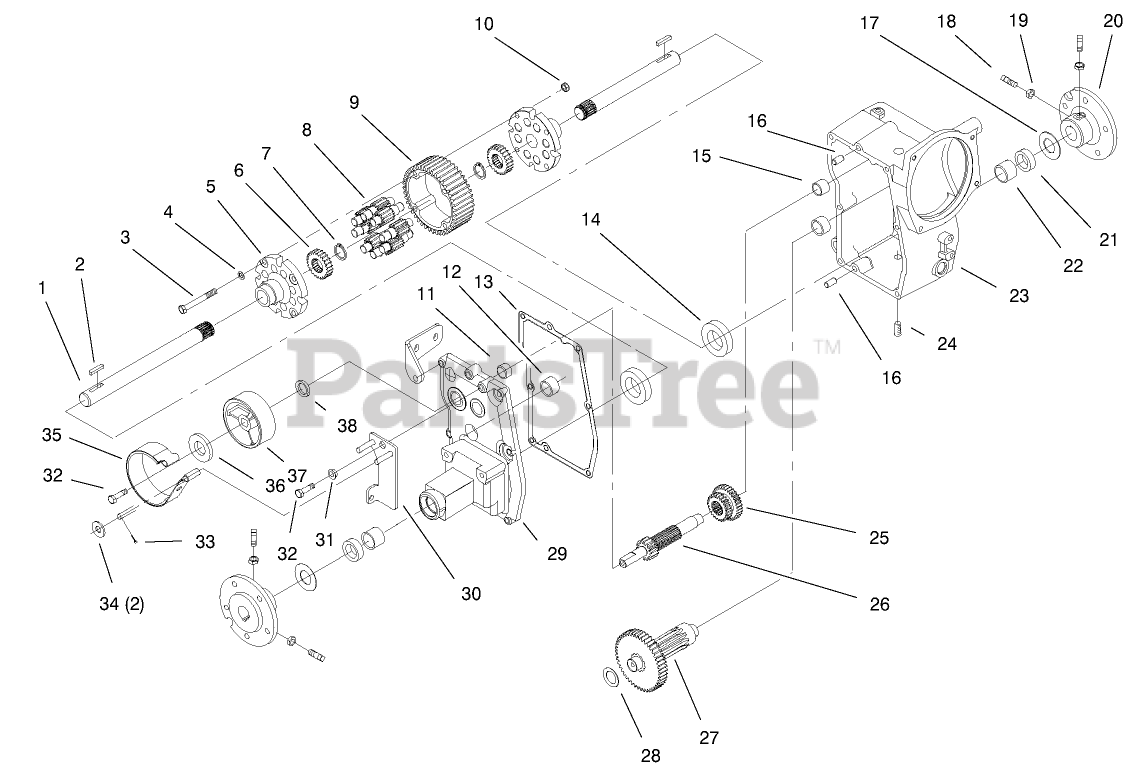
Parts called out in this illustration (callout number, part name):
1	AXLE-REAR
4	WASHER
5	END CAP-DIFFERENTIAL
6	GEAR-AXLE DIFFERENTIAL
7	RING-SNAP
8	GEAR-PINION, 11T
9	GEAR-DIFFERENTIAL RING, 43T
10	NUT-HEX
11	BEARING-NEEDLE
13	GASKET-CASE
14	BEARING-BALL
15	BEARING-NEEDLE
16	PIN-LOCATING
17	WASHER-THRUST
18	SCREW-SET, SQH
19	NUT-JAM
20	HUB-WHEEL
21	SEAL-OIL
22	BEARING
24	PLUG-PIPE
25	GEAR-SLIDING
26	SHAFT-BRAKE
27	GEAR ASM
28	WASHER-THRUST
30	ARM-PIVOT, BRAKE (BLACK)
31	CAM-SPACER
32	SCREW-HH, LOCK
33	PIN-COTTER
34	WASHER-FLAT
35	BAND-BRAKE
36	WASHER
37	DRUM-BRAKE
38	SEAL-OIL
